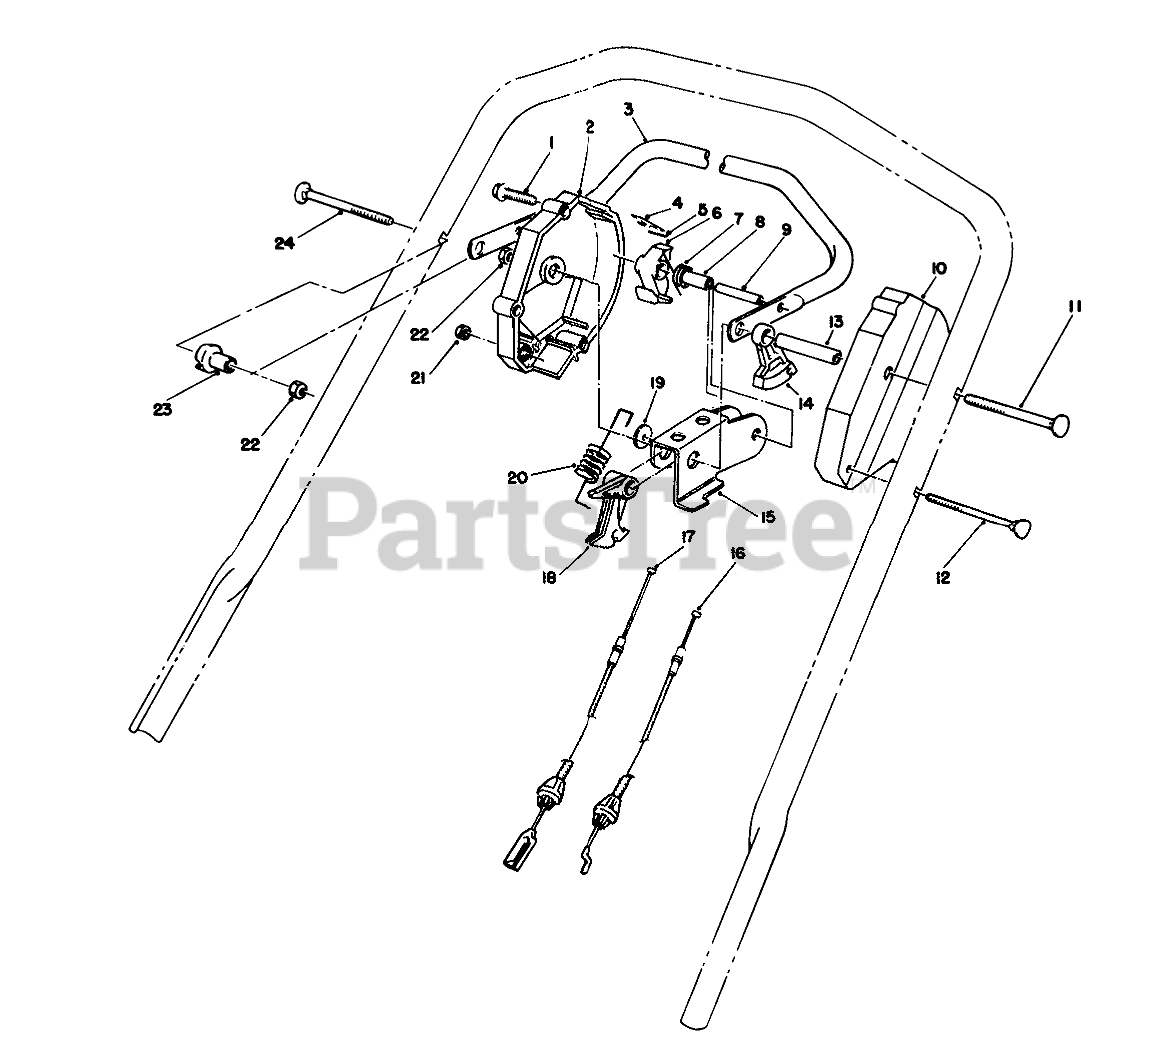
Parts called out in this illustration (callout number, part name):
1	SCREW-HWHTF
2	Housing-Control
3	Bar-Control
4	SPRING-LEAF
5	PIN-INSERT
6	HOOK-CONTROL
7	SPRING-TORSION
8	SPACER
9	PIN-ROLL, SLOTTED
10	HOUSING-CONTROL, LH
11	Screw-Handle
12	HANDLE SCREW
13	TUBING-SPACER
14	LEVER-TRACTION
15	ROCKER
16	Cable-Traction
17	Cable-BBC
18	LEVER-CABLE
19	WASHER-NYLON
20	SPRING-DETENT
21	NUT-HEX
22	NUT-LOCK, NI
23	SPACER-SUPPORT
24	SCREW-HANDLE
